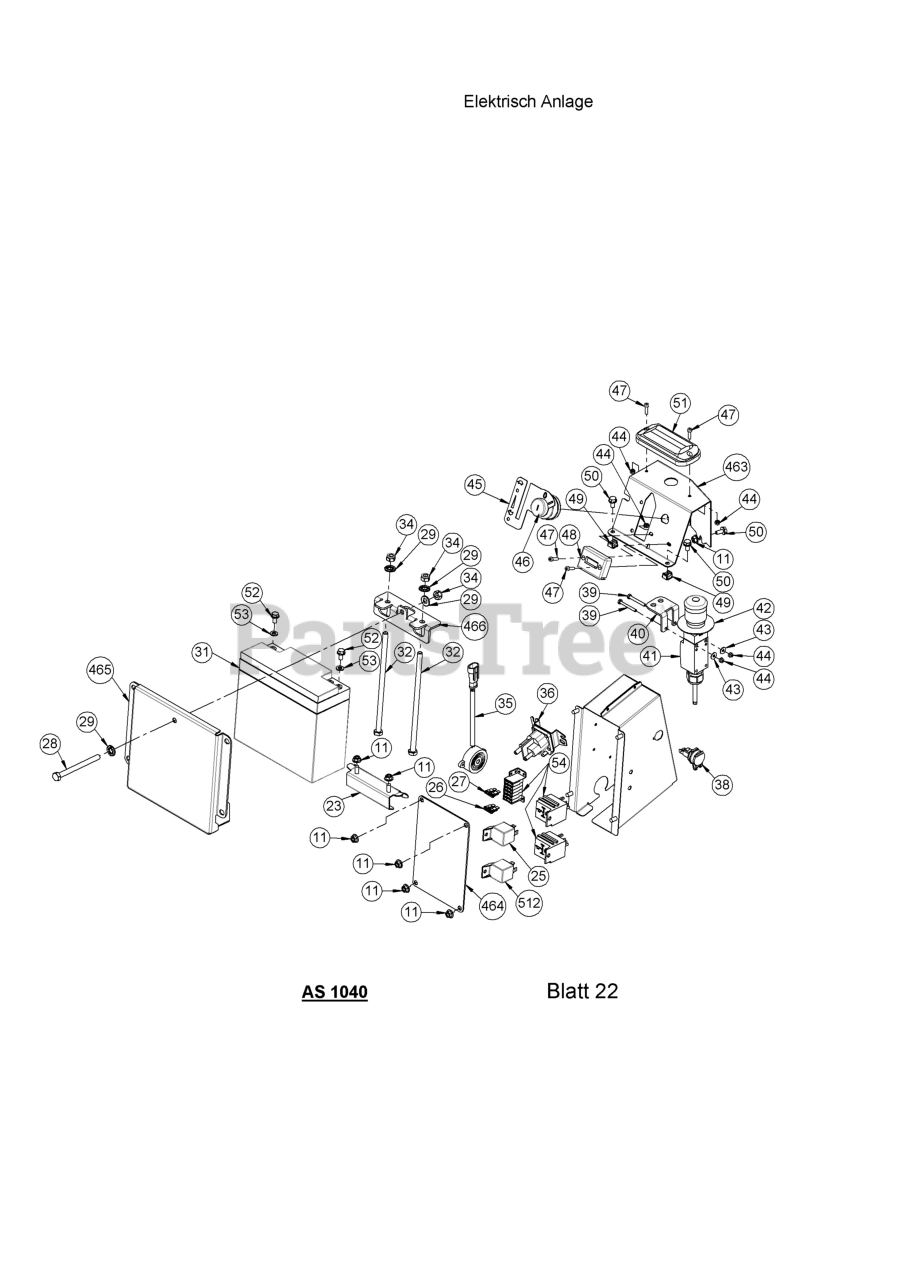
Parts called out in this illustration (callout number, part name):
11	NUT, FLG SLF LK M6 CL 8 ZCC
23	BRACKET, WIRE HARNESS
25	RELAY, W/BRACKET-12V 40A SPDT
26	FUSE, 25A
27	FUSE-10 AMP ATC TYPE
28	BLT, HEX M8X95 DIN 931 8.8 ZCC
29	WSHR, LK-EDGE SKM8(8.2X18X1.4)
31	"BATTERY, MP22-12C (12V 22 AH)"
32	BLT, HEX M8X190 DIN 931 8.8 ZCC
34	NUT, LK-NYL M8 DIN 985 8 ZCC
35	ALARM, AUDIBLE
36	SOLINOID, STARTER
38	PORT, 12 VOLT POWER
39	BLT, HEX M4X35 DIN 933 8.8 ZCC
40	BRACKET, EMERGENCY STOP SWITCH
41	SWITCH, EMERGENCY STOP
42	DECAL, E STOP
43	WSHR, FLT M4.3 DIN 9021 ZCC
44	NUT, LK NYL M4 DIN 985 8 ZCC
45	PLATE, THROTTLE & IGNITION
46	SWITCH, IGNITION W/O KEY
47	SCR, SKH M4X16 DIN ISO 4762 8.8
48	HOUR METER
49	NUT, CAGE M6
50	BLT, FLG SLF LK M6X12
51	LIGHT, STROBE
52	BLT, FLG M6X12 DIN 6921 8.8 ZCC
53	WHSR, FLT M6.4 DIN 125 ST  ZCC
54	HARNESS, OVIS MAIN
463	PANEL, CONTROL
464	COVER, ELECTRICAL PANEL
465	HOLDER, BATTERY
466	BRACKET, BATTERY UPPER
512	RELAY, 70A
